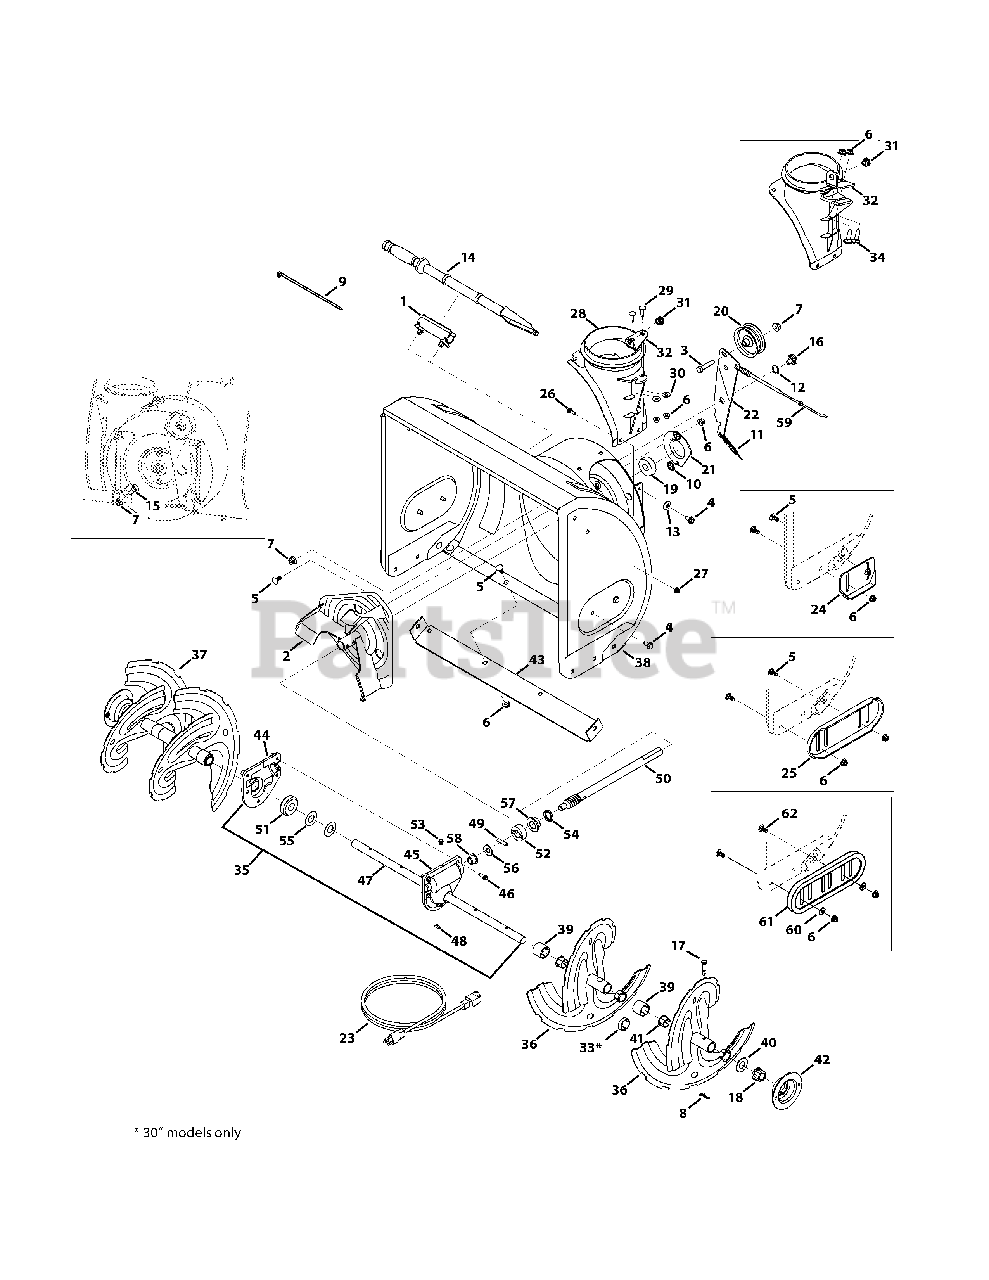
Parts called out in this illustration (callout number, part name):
1	Cleanout Tool Mount
2	Impeller Assembly, 12"
3	Hex Screw, 3/8-16 x 1.75
4	Hex Washer Screw, 5/16-18 x .750
5	Carriage Bolt, 5/16-18 x .750
6	Flange Lock Nut, 5/16-18
7	Flange Lock Nut, 3/8-16
8	Bow-Tie Cotter Pin
9	Cable Tie, 3/16 x .05 x 7.4
10	Push Nut, .25 Dia.
11	Extension Spring
12	Wave Washer, .625 x .885 x .015
13	Bell Washer, .340 x .872 x .060
14	Chute Cleanout Tool
15	Shoulder Bolt, .496 x .336 x 3/8-16
16	Shoulder Screw, .625 x .17 x 3/8-16
17	Shear Pin, .25 x 1.50
18	Hex Flange Bearing, .75 ID
19	Ball Bearing, .75 ID x 1.85 OD
20	Idler Pulley, 2.75 OD
21	Bearing Housing, 1.85 ID
22	Auger Idler Bracket
23	Extension Cord
24	Skid Shoe
25	Deluxe Skid Shoe - Black
25	Deluxe Skid Shoe - Green
25	Deluxe Skid Shoe - Red
26	Carriage Screw, 1/4-20 x .75
27	Flange Lock Nut, 1/4-20
28	Chute Adapter, 5"
28	Chute Adapter, 5" (4-way)
29	Carriage Screw, 5/16-18 x 1.00
30	Flat Washer, .349 x .879 x .063
31	Plastic Bushing, .380 ID
32	Chute Crank Bracket
32	Chute Crank Bracket, Big Block Engines
33	Spacer, 1.250 x .75 ID x 3/16 LG
34	Carriage Bolt, 5/16-18 x 1.00
35	Gearbox Assembly, 22"
35	Gearbox Assembly, 24"
35	Gearbox Assembly, 26"
35	Gearbox Assembly, 28"
35	Gearbox Assembly, 30"
36	Spiral Assembly, LH - Grey
36	Spiral Assembly, LH - Black
37	Spiral Assembly, RH - Grey
37	Spiral Assembly, RH - Black
38	Auger Housing Assembly, 22" - Red
38	Auger Housing Assembly, 24" - Black
38	Auger Housing Assembly, 24" - Green
38	Auger Housing Assembly, 24" - Red
38	Auger Housing Assembly, 26" - Black
38	Auger Housing Assembly, 26" - Green
38	Auger Housing Assembly, 26" - Red
38	Auger Housing Assembly, 28" - Black
38	Auger Housing Assembly, 28" - Green
38	Auger Housing Assembly, 30" - Black
38	Auger Housing Assembly, 30" - Red
39	Spacer, 1.2500 x .75 ID x 1.00
40	Flat Washer, .76 x 1.49 x .06
41	Flange Bushing, .800 ID x .910 OD
43	Shave Plate, 22" - Red
43	Shave Plate, 24" - Black
43	Shave Plate, 24" - Green
43	Shave Plate, 24" - Red
43	Shave Plate, 26" - Black
43	Shave Plate, 26"- Green
43	Shave Plate, 26" - Red
43	Shave Plate, 28" - Black
43	Shave Plate, 28"- Green
43	Shave Plate, 30" - Black
43	Shave Plate, 30" - Red
44	Housing Assembly, RH
45	Housing Assembly, LH
46	Hex Washer Screw, 1/4-20 x .750
47	Auger Axle, 22"
47	Auger Axle, 24"
47	Auger Axle, 26"
47	Auger Axle, 28"
47	Auger Axle, 30"
48	Hi-Pro Key
49	Dowel Pin, .25 OD x 1.25 LG
50	Worm Shaft, .75 OD
51	Worm Gear 20 T, 24",26",28"& 30"
51	Worm Gear 20 T, 22"
52	Thrust Collar, .756 ID x .600
53	Plug, 1/4 x .437
54	Oil Seal, .75 x 1.131 x .188
55	Flat Washer, .760 ID x 1.50 ID
56	Flat Washer, .51 x 1.12 x .06
57	Flange Bearing, .75 ID x 1.0 OD x .59
58	Flange Bearing, .50 ID x .75 OD x .59
59	Auger Drive Cable
60	Washer, Flat, .349 x .879
61	Slide Shoe, Polymer
61	Deluxe Polymer Reversible Shoe Kit
62	Carriage Screw, 5/16-18 x 1.00
